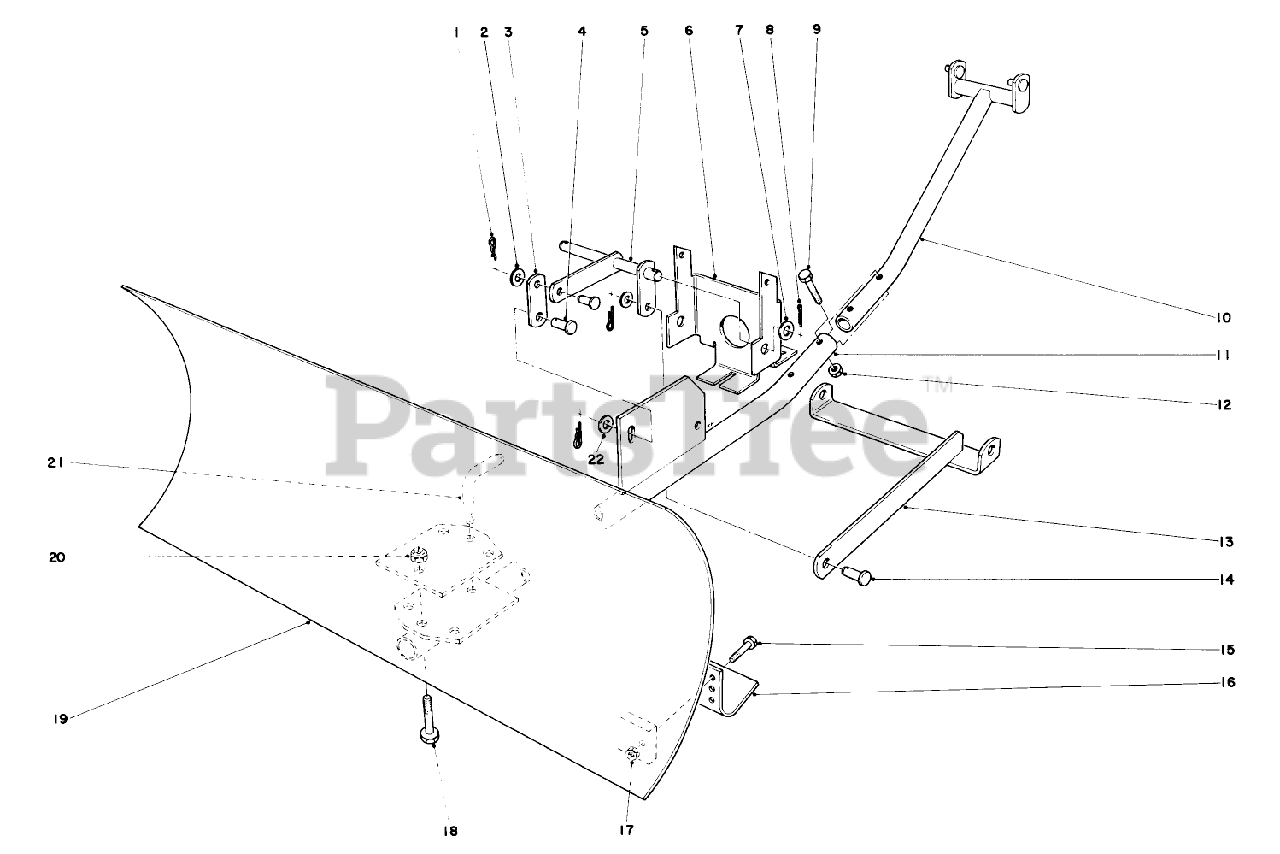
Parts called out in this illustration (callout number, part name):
1	PIN-COTTER, HAIR
2	WASHER-FLAT
3	Linkage
5	Lift Linkage
6	Bracket Mounting
7	WASHER-FLAT
8	PIN-COTTER
9	SCREW-HH
10	Connecting Tube
11	Snowblade Tongue
12	NUT-LOCK, SIDE
13	Linkage Rear
14	PIN-CLEVIS
15	SCREW-HH
17	NUT-HEX, SIDE DEFORM
18	SCREW-HH
19	Blade
20	1/2-13 CONELOCK NUT
21	Pivot Pin
22	WASHER-FLAT
